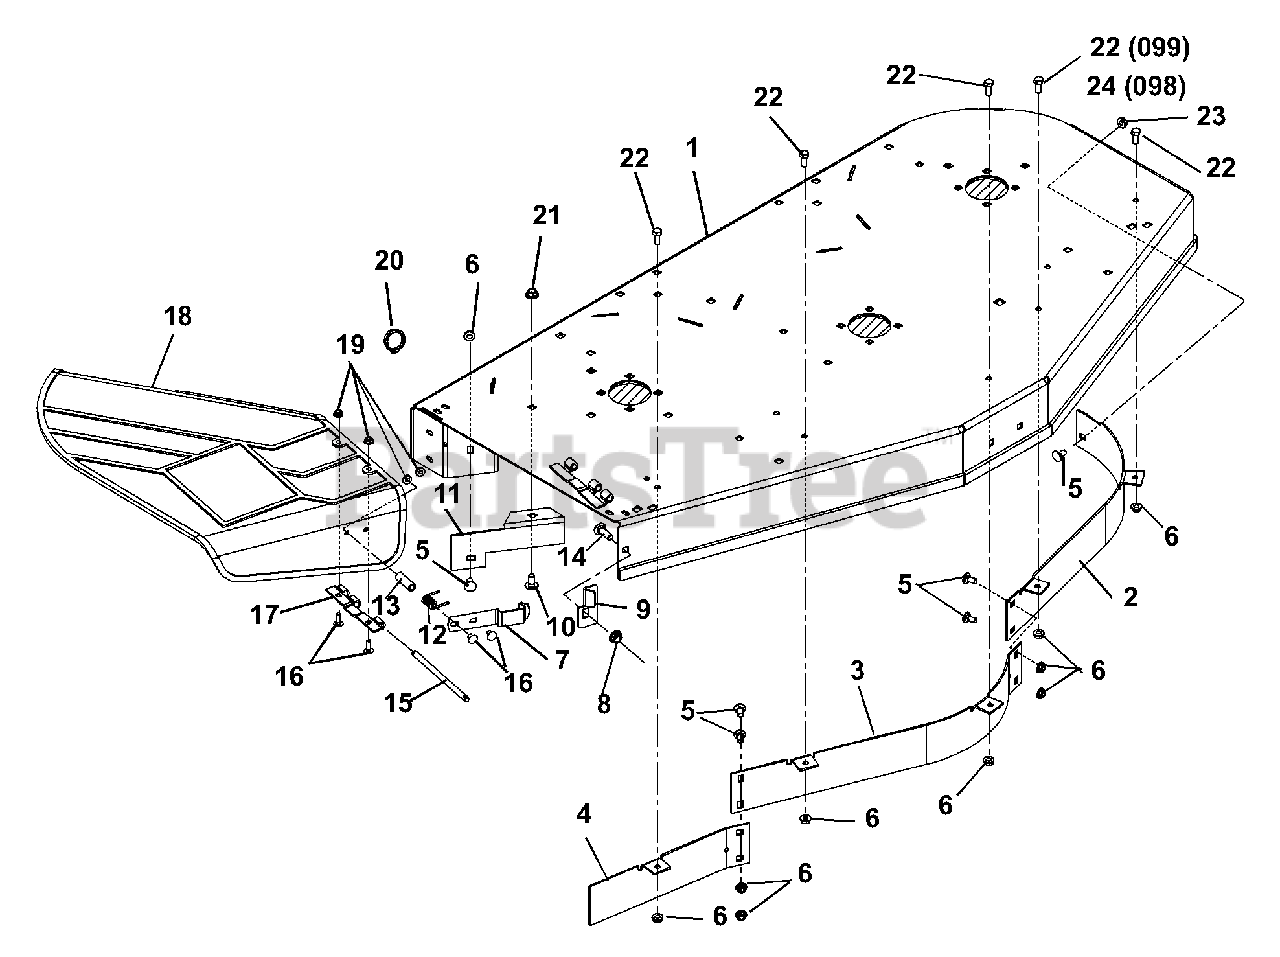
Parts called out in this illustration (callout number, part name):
1	WMT, DECK 48" CONSUMER CZ
1	WMT, DECK 44" CONSUMER CZ
2	BAFFLE - LEFT FRONT - 48"
2	BAFFLE - LEFT FRONT - 44"
3	BAFFLE - CENTER FRONT - 48"
3	BAFFLE - CENTER FRONT - 44"
4	BAFFLE - RIGHT FRONT - 48"
4	BAFFLE - RIGHT FRONT - 44"
5	@BLT-RHDSSQNK .31-18X.62 G5YZ
6	@NUT-LK-NYL-FLG .31-18 YWZC
7	FLAT SPRING
8	@NUT-LK-TOP-FLG .38-16 YWZC
9	BRACKET, CHUTE LOCK
10	@BLT-RDHDSQNK .38-16X.75 G5YZ
11	DEFLECTOR-44"/48"
12	SG-TORS .095X.50X 1.0
13	BSHG-SLV .334 X .502 X 1.437
14	@BLT-RDHDSQNK .38-16X1.25 G5YZ
16	@BLT-RDHDSQNK .25-20X.75 G5YZ
17	HINGE PLATE
18	DEFLECTOR, CHUTE
19	@NUT-LK-NYL-FLG .25-20 YWZC
20	RG-RTNG-EXT .312X.025
21	@NUT-LK-NYL-FLG .38-16 YWZC
22	@BLT-HEX .38-16X1.00 GR5 YWZC
23	@NUT-LK-CTR-JAM .31-18 YWZC
24	@BLT-HEX .31-18X1.00 GR5 YWZC
